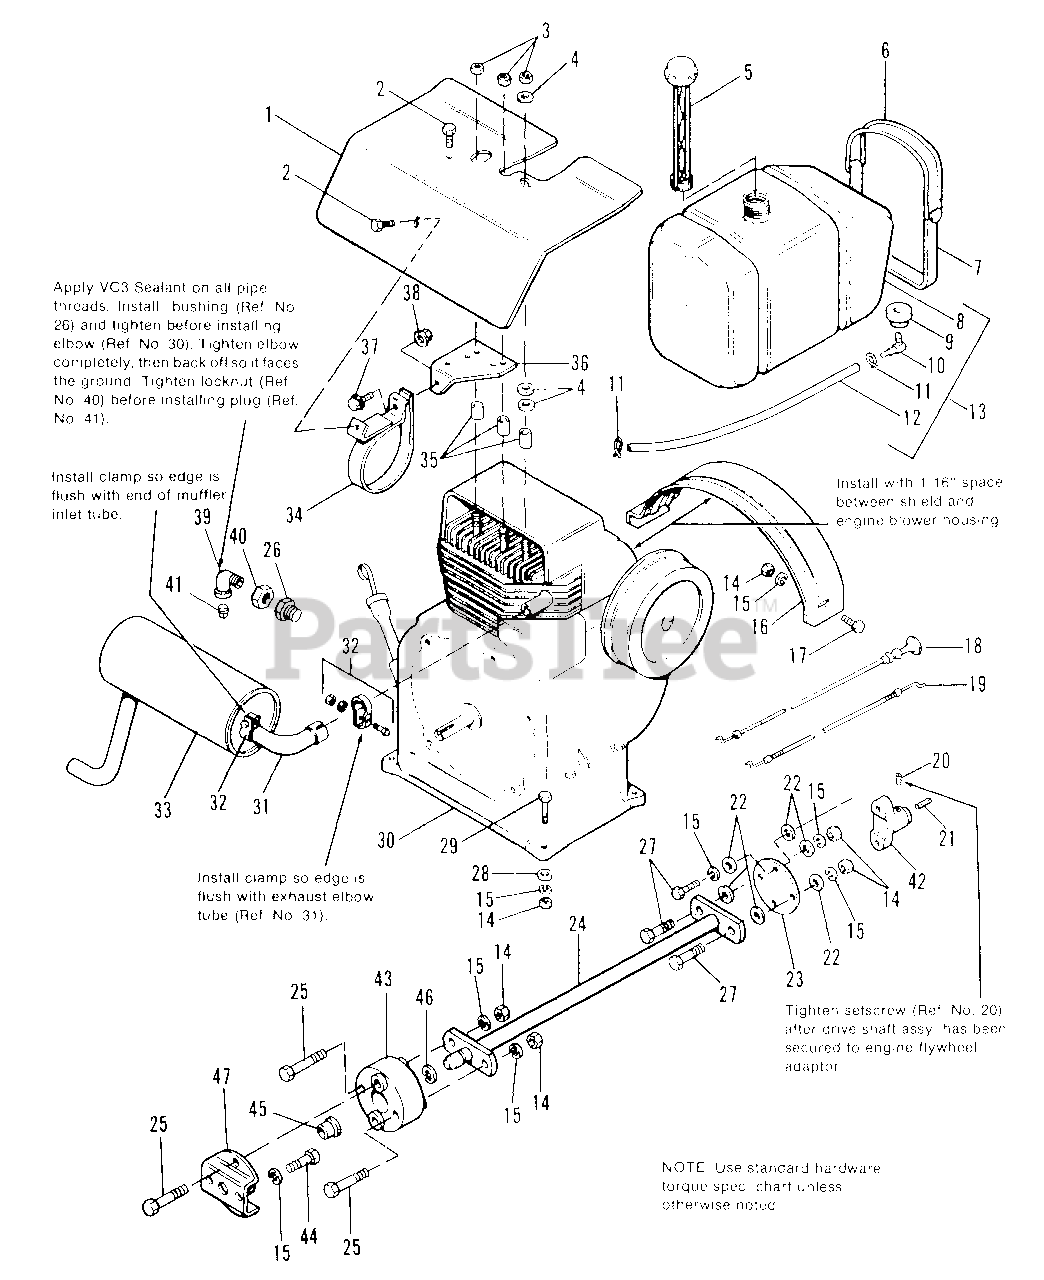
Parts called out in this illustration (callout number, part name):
1	SHIELD, Heat
2	SCREW, Hex, Taptite, 1/4-20 x 1/2
3	LOCKNUT, Hex, Jam, 3/8-16
5	CAP, Fuel Tank
6	STRAP, Fuel Tank
7	STRAP, Tank
11	CLAMP, Hose
13	TANK ASSY., Fuel
14	NUT, Hex, Full, 3/8-16
15	LOCKWASHER, 3/8-16
17	CAPSCREW, Hex Hd., 3/8-16 x 1
18	CONTROL, Choke
19	CONTROL, Throttle
20	SETSCREW, 3/8-24 x 3/8
21	KEY, Drive Shaft
22	WASHER, Special
24	SHAFT ASSY., Drive
26	CAPSCREW, Hex Hd., 3/8-16 2-1/2
26	BUSHING, Pipe, 3/4 x 3/8
27	CAPSCREW, Hex Hd., 3/8-16 x 1-1/4
28	WASHER, Plain, 3/8
29	CAPSCREW, Hex Hd., 3/8-16 x 1-1/2
30	ENGINE, 14HP Kohler
31	ELBOW, Exhaust
32	CLAMP, Muffler
33	MUFFLER, Exhaust
34	STRAP ASSY., Muffler
36	SUPPORT, Muffler
37	CAPSCREW, Hex, Whiz, Flange, 5/16-18 x 1-1/2
38	NUT, Hex, Flange, 5/16-18
39	ELBOW, Pipe, 90ø, 3/8
40	LOCKNUT, 3/8-18
41	PLUG, Pipe, 3/8
42	FLANGE, Drive Shaft
43	COUPLING, Compression
44	CAPSCREW, Hex Hd., 3/8-16 x 3/4
46	RING, Retaining
47	PLATE ASSY., Adaptor
